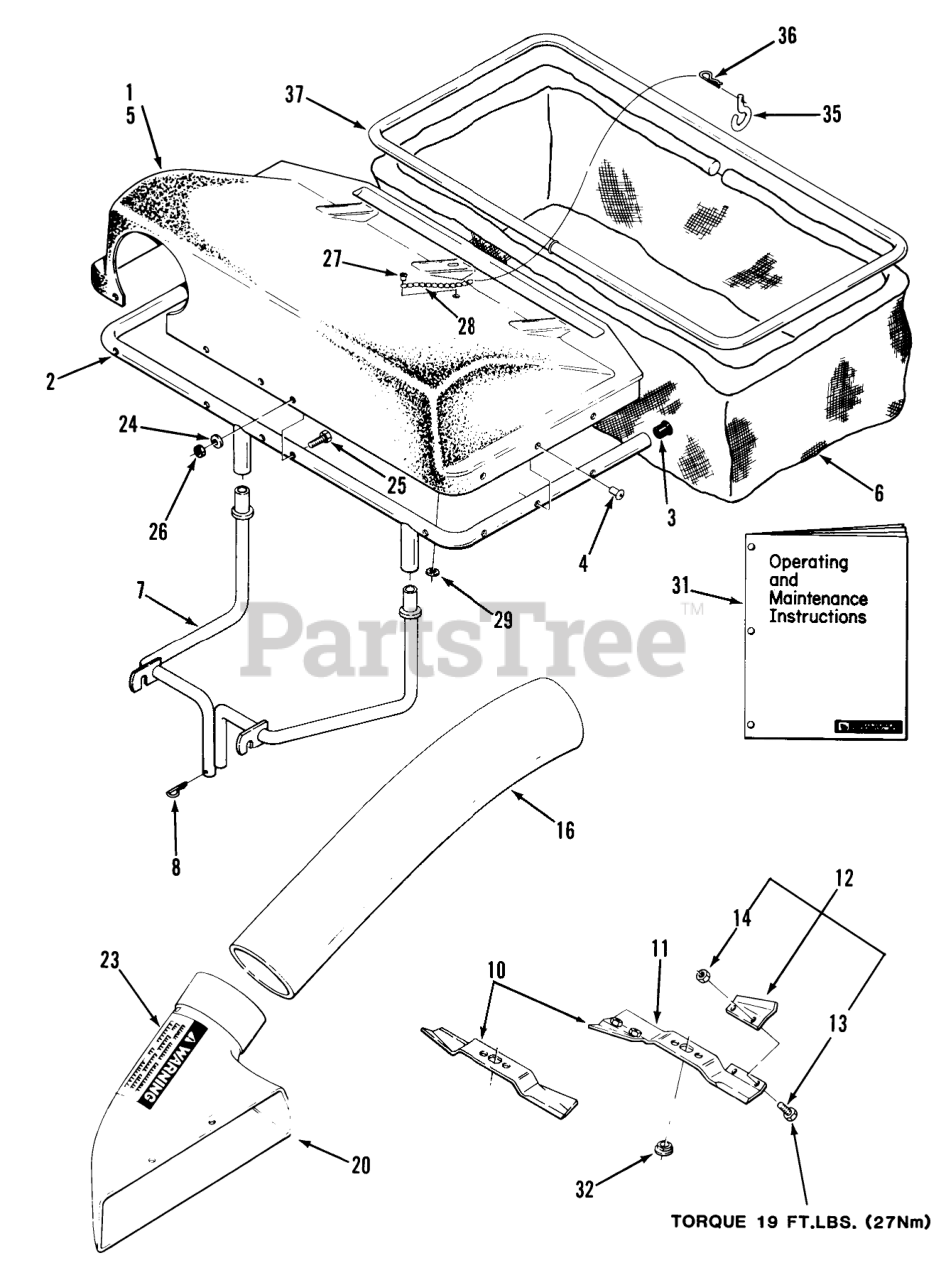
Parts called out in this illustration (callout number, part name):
4	Poprivet 3/16 dia. x .575
8	Hairpin
10	KIT-BLADE (SERVICE)
11	ASSY-HI LIFT BLADE
12	S/A 37 LIFT TAB KIT
13	BOLT 5/16-18X5/8
14	NUT-HEX
27	RIVET
31	Operating and Maintenance Instructions
32	SPACER BLADE
36	Hairpin Cotter
37	FRAME-BAG *B
